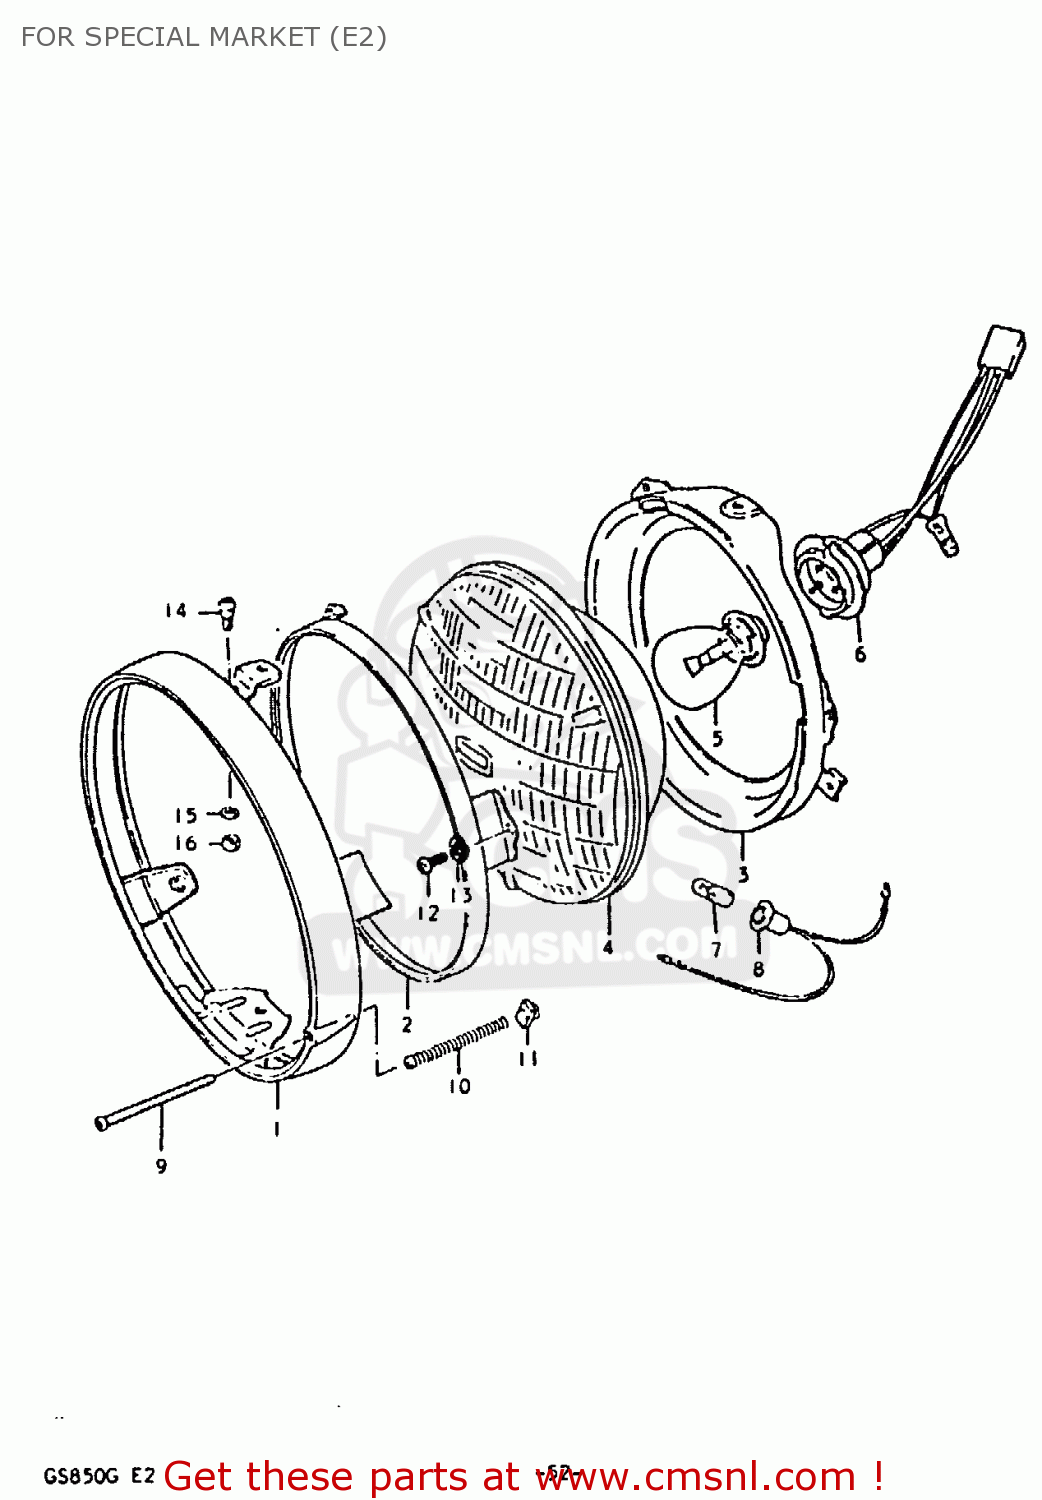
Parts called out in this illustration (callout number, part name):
1	RIM
2	RETAINING RING
3	RING
4	LAMP UNIT
5	BULB
6	SOCKET,HEADLAMP
7	BULB
8	SOCKET
9	SCREW,HEADLAMP ADJUST
10	SPRING,ADJUSTING
11	NUT
12	SCREW
13	LOCK WASHER
14	H/LAMP LENS UNIT FITING SCRE
15	LOCK WASHER
16	NUT
